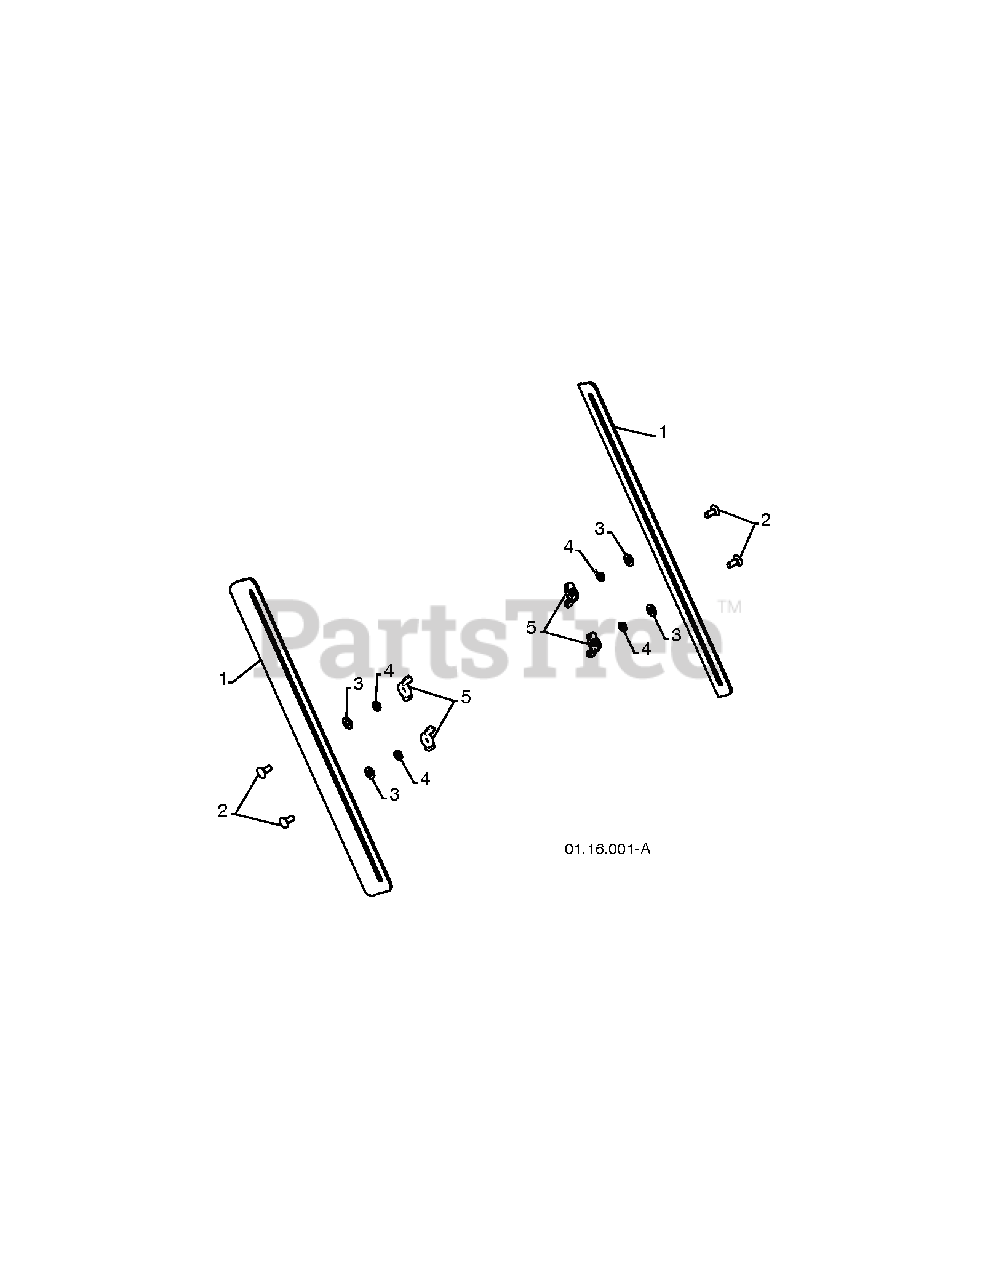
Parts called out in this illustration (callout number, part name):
1	RP BAR.DRIFT.CUTTER
3	WASHER, NYLON FRICTION
4	LOCKWASHER
5	NUT WING PM
